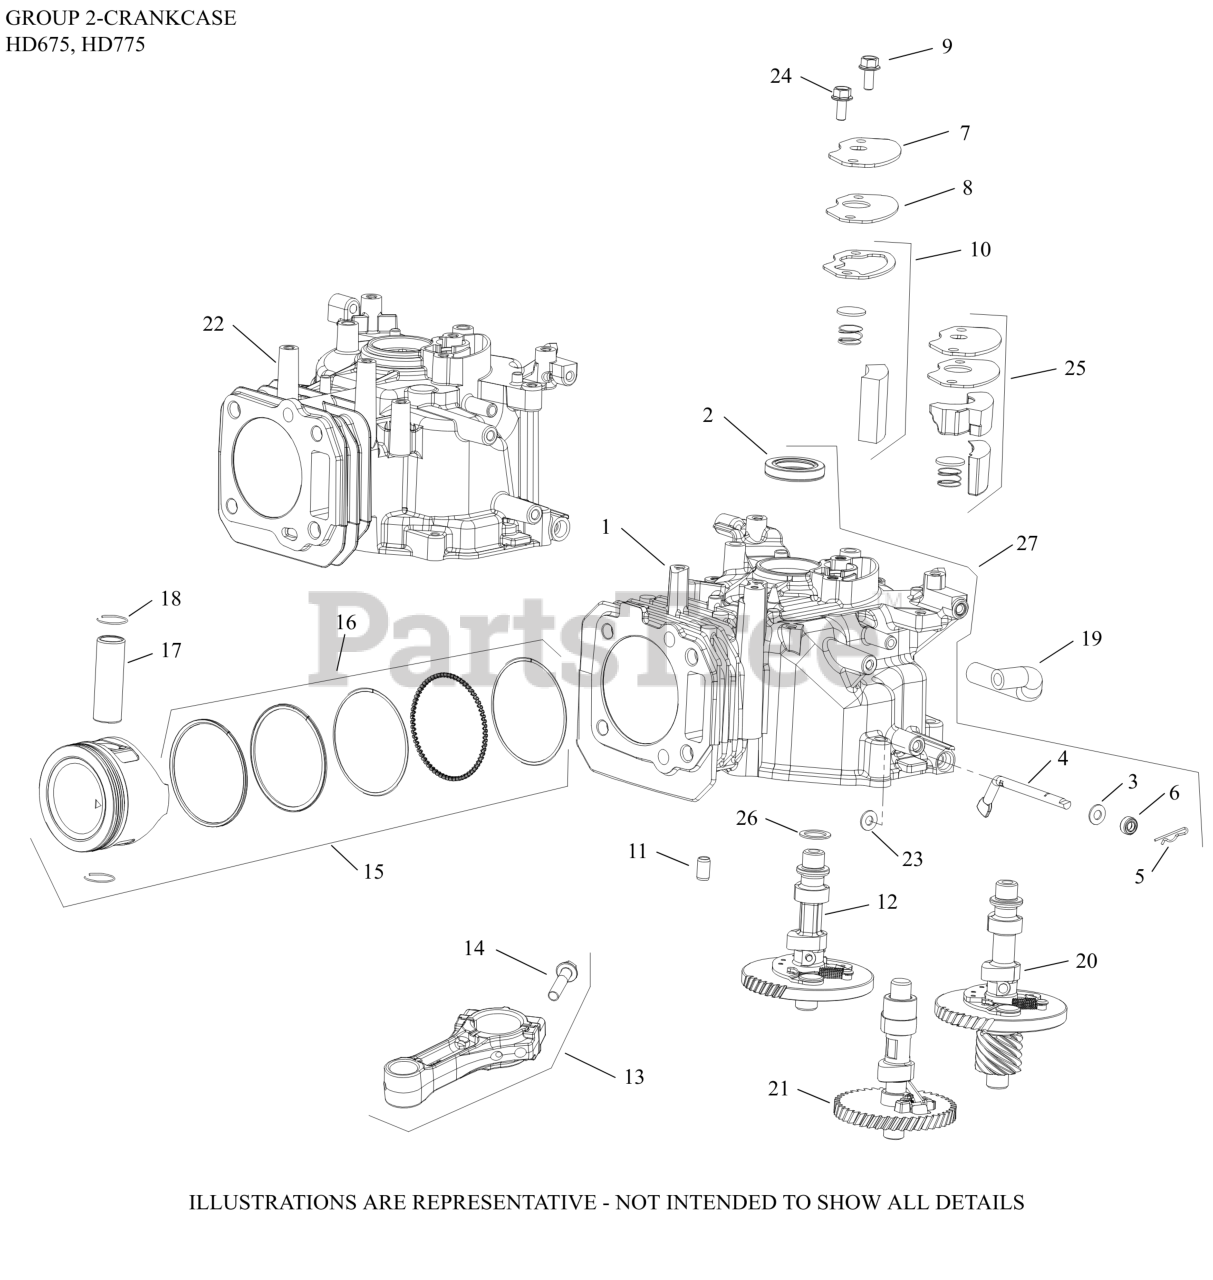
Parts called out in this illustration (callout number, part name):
1	CRANKCASE
2	SEAL, CCASE/FLYWHEEL
4	SHAFT, GOVERNOR CROSS
5	CLIP, GOVERNOR SHAFT
6	SEAL, OIL
7	COVER, BREATHER
8	GASKET, BREATHER COVER
10	KIT, BREATHER FILTER
11	PIN, DOWEL (8mm)
12	CAMSHAFT ASSEMBLY
13	CONNECTING ROD
14	SCREW, HEX FLANGE (M7)
15	KIT, PISTON
17	PIN, PISTON
18	RETAINER, PISTON PIN
19	HOSE, BREATHER
23	WASHER, FLAT (DIA 13mm O.D.)
24	SCREW, HEX FLANGE (M6)
25	KIT, BREATHER FILTER
29	FILTER, BREATHER MEDIA-USE 14 050 31-S
